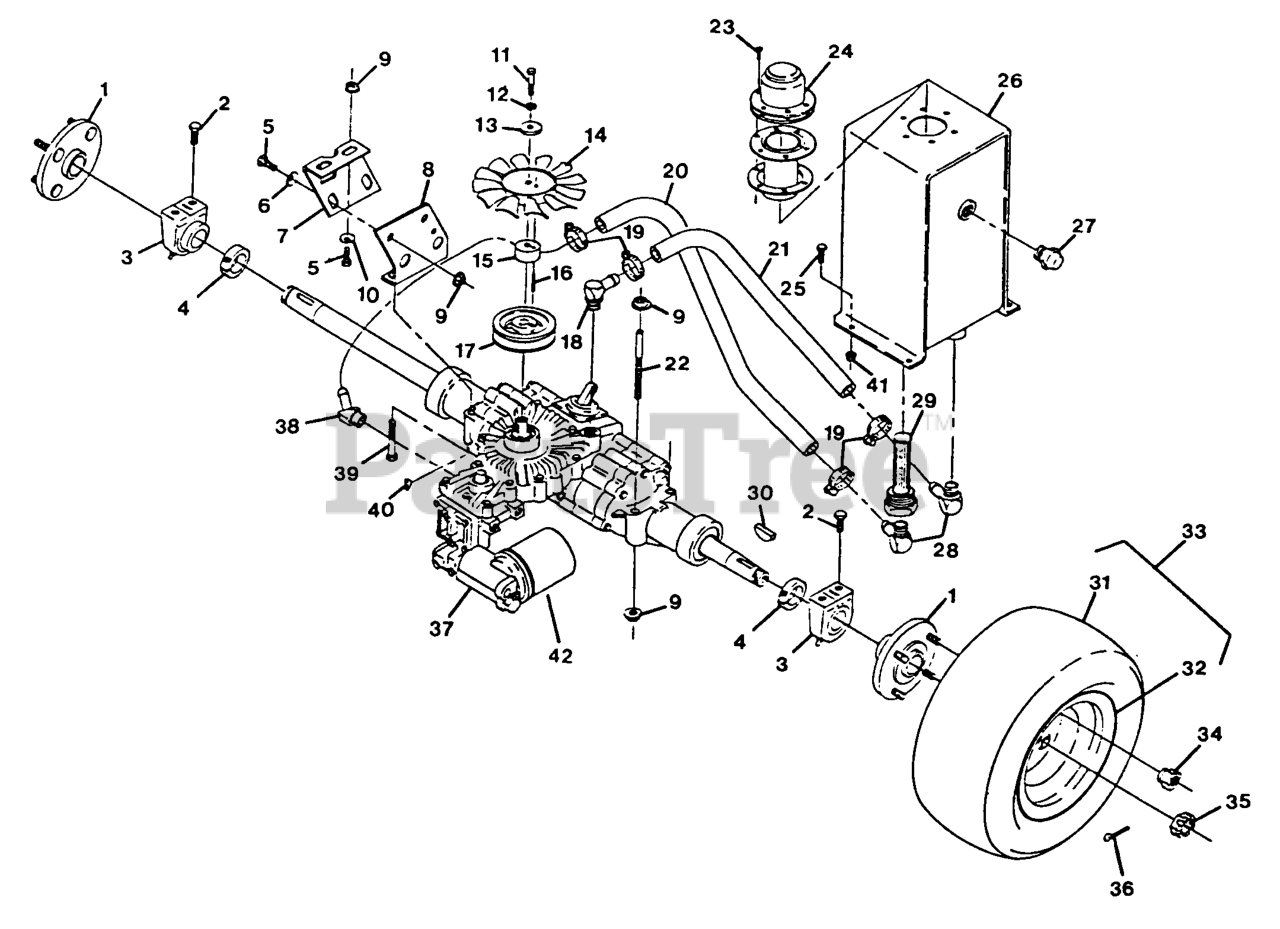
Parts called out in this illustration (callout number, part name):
3	BEARING,PILLOW BLOCK
12	WASHER-LOCK
13	WASHER-RETAINER, PULLEY
14	FAN,7"OD/10BLADE
15	SPACER,FAN
19	CLAMP-HOSE
20	HOSE,HYDRAULIC 16.5
21	HOSE,HYDRAULIC 8.0
22	PIN,GUIDE
24	BREATHER,FILLR & CAP
27	OIL EYE,HYDRAULIC TANK
29	STRAINER,SUCTION
33	WHEEL AND TIRE ASM
36	PIN-COTTER
38	ELBOW-45DEGOR/HSEBRB
